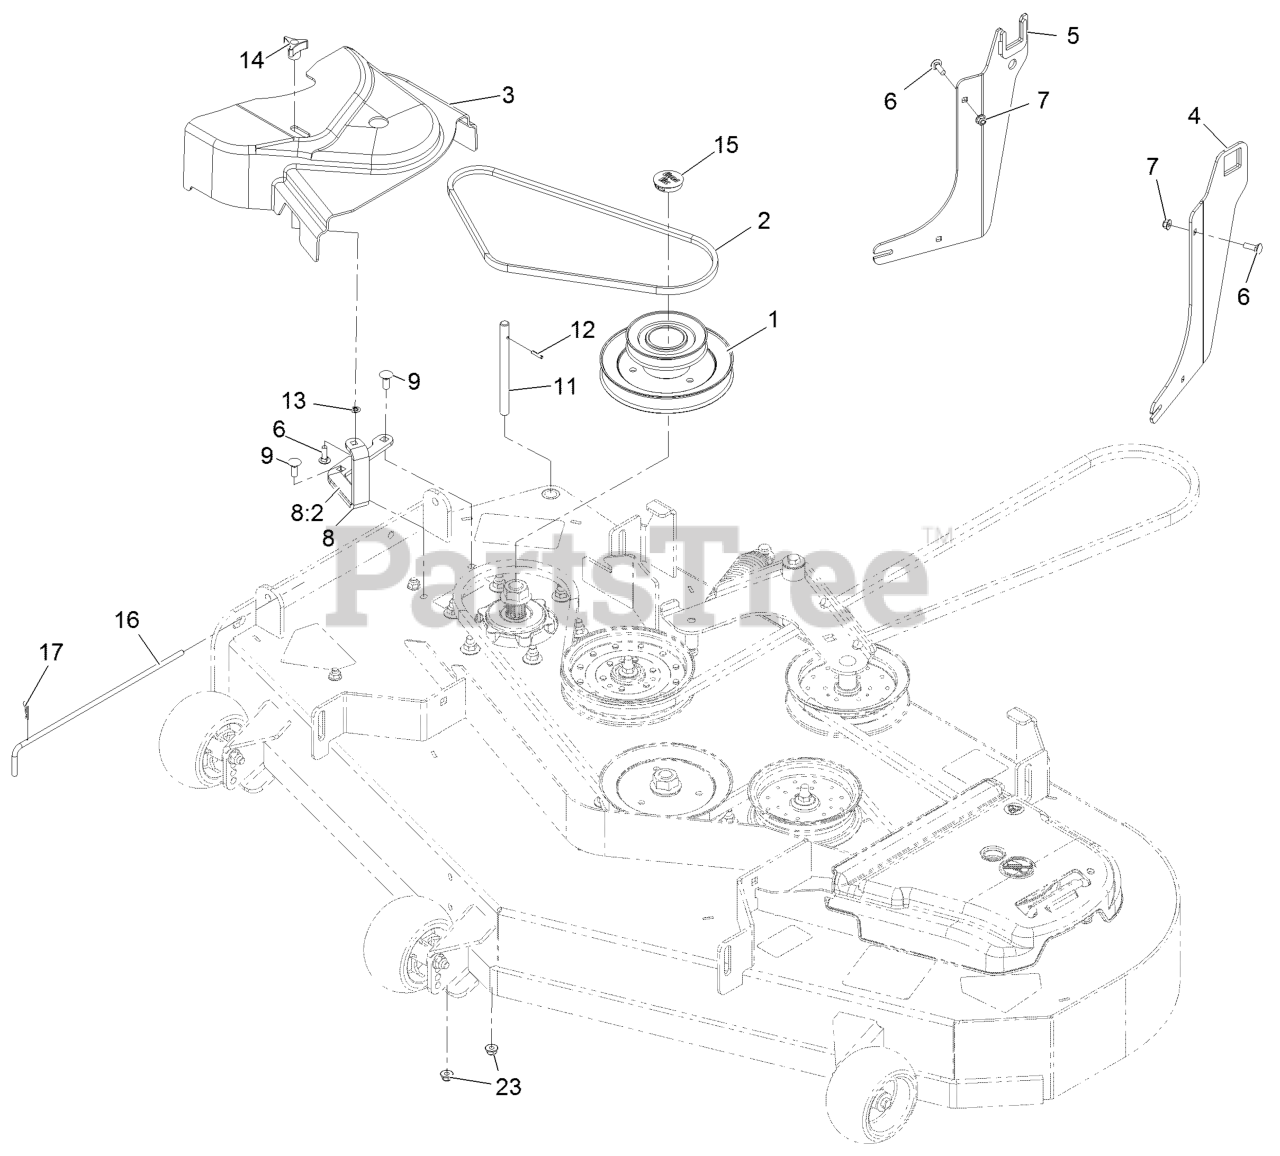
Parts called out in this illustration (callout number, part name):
1	JACKSHAFT,UV DRIVE 524 SP
2	BELT-BLOWER
3	COVER-BELT, UV 52
4	BRACKET ASM, LH
5	BRACKET ASM, RH
6	BOLT-CARR
7	NUT-HF, NI
8	ASM-CVR BRKT W/DECAL
8:2	DECAL-DANGER
9	BOLT-CARR
11	SHAFT-CATCHER, GRASS
12	PIN-ROLL
13	RING-RETAINING, BOLT
14	KNOB-3 PRONG
15	PLUG, BLACK NYLON 1.75
16	PIN,CHUTE PIVOT
17	PIN-COTTER
23	Nut-Nyloc 3/8-16 Flg
